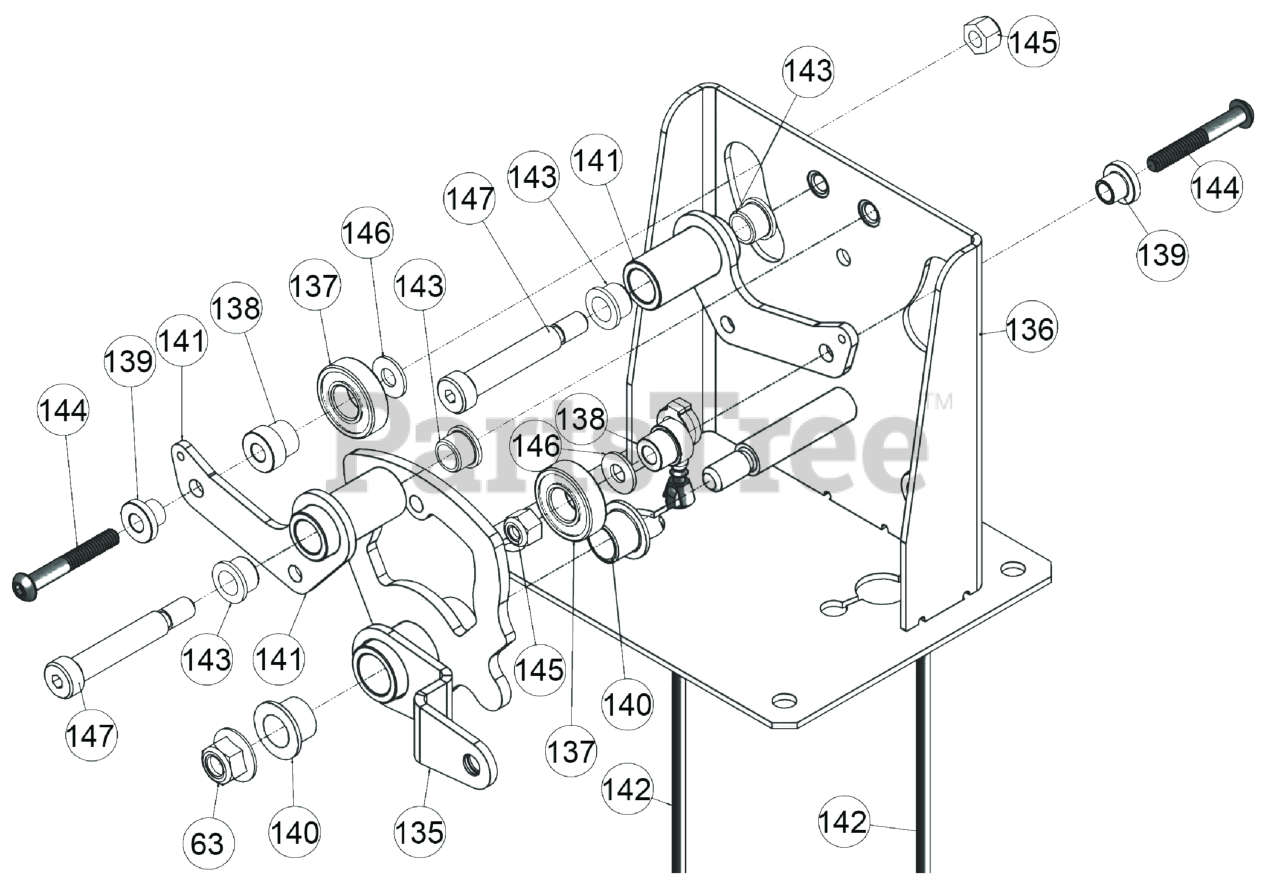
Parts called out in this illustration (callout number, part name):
63	NUT-HEX-NYLK, FLG .375"-16 ZP
135	CAM, SPEED CONTROL WA
136	BRACKET, SPEED CONTROL WA
137	BEARING 1/2" ID X 1.125 OD
138	SPACER. SPEED CONTROL STEPPED PM
139	SPACER, SPEED CONTROL EYELET PM
140	BUSHING .500" ID
141	BELLCRANK SPEED CONTROL BC26
142	SEE: 501276-S
143	BUSHING 3/8 ID X 1/2 OD X 3/8
144	SCREWCAP 1/4-20 X 1 3/4 SKT BUT HD
145	NUT LOCK 1/4"-20 HEX Z/P
146	WASHER 1/4"SAE9/32"X5/8"X1/16"
147	BOLT SHOULDER 3/8" X 1 3/4"
